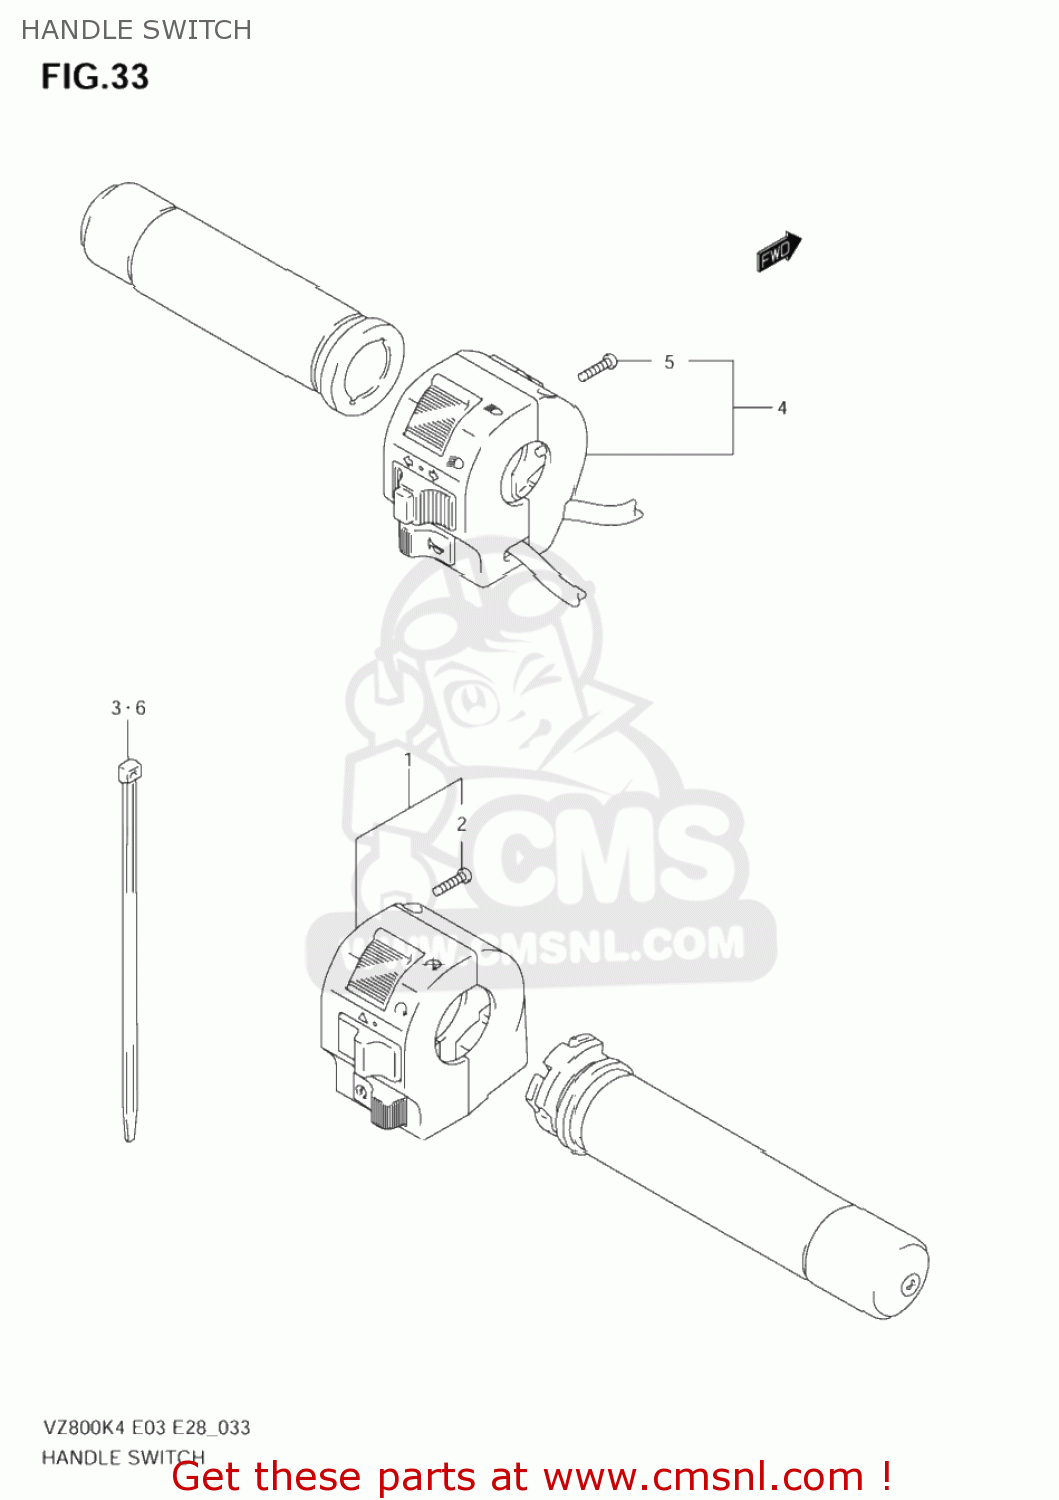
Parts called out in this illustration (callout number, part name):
1	SWITCH ASSY,HANDLE,R
2	SCREW(5X16)
3	CLAMP(L:145)
4	SWITCH ASSY,HANDLE,L
5	SCREW(5X16)
6	CLAMP(L:145)
